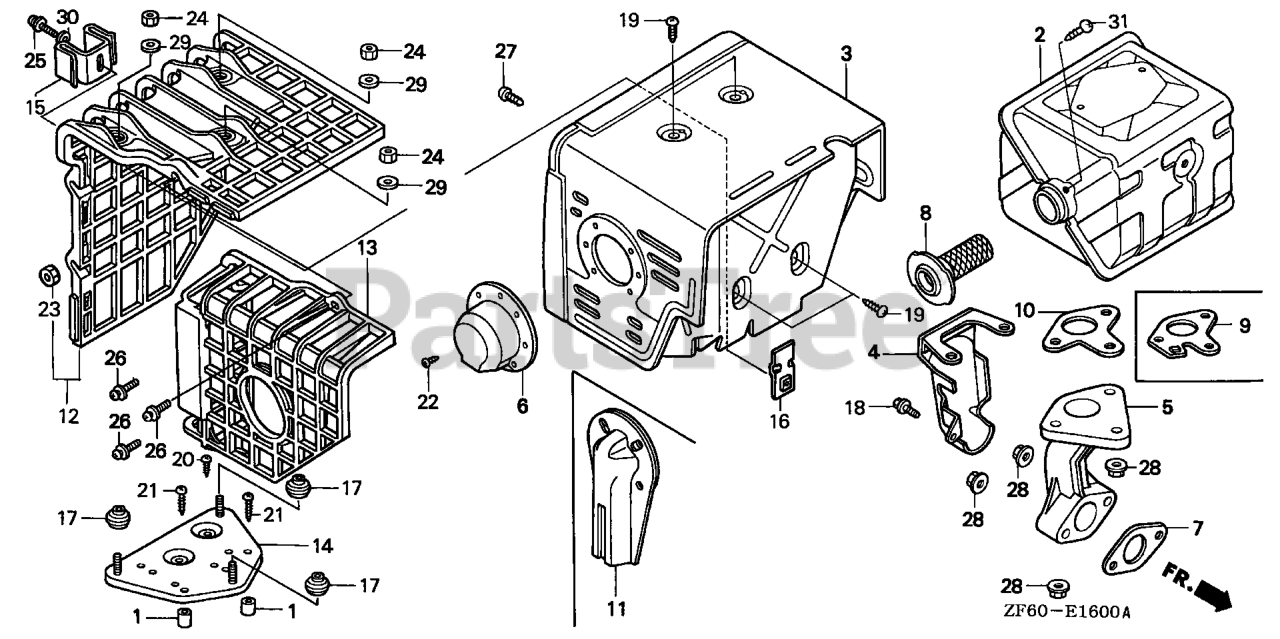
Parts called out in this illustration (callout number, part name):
2	MUFFLER (100DB)
3	PROTECTOR, MUFFLER
4	PROTECTOR, EX. PIPE
6	CAP, MUFFLER
7	GASKET, EX. PIPE Use up to Engine SN 2949254.
7	GASKET, EX. PIPE (WACKER)
8	ARRESTER, SPARK
9	GASKET, MUFFLER (ARRESTER)
18	BOLT, FLANGE (6X12) (CT200)
19	SCREW, TAPPING (5X8)
22	SCREW, TAPPING (4X6) (TO INSTALL OPTIONAL SPARK ARRESTER)
27	SCREW, TAPPING (6X10)
28	NUT, FLANGE (8MM)
31	SCREW, TAPPING (5X8)
31	SCREW, TAPPING (4X6) (TO INSTALL OPTIONAL SPARK ARRESTER)
